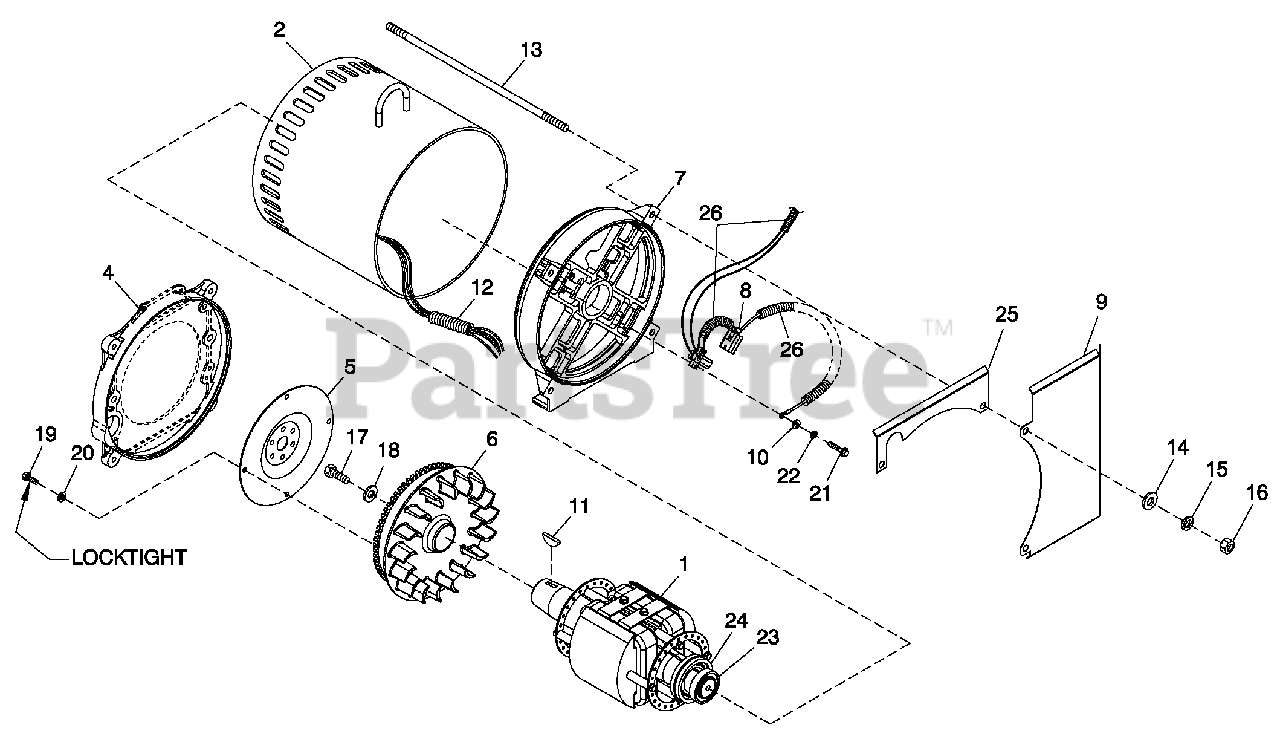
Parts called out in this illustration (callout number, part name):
1	ROTOR-2390-35KD1 CPL
2	STATOR-2390-35AD1 CPL
4	ENGINE ADAPTER
5	FLEXPLATE
6	ASSY FLYWHEEL CPL W/40MM FAN B
7	REAR BEARING CARRIER 390/DRCT
8	ASSY BRUSH HOLDER 390/HSB
9	GUARD REAR BEARING CARRIER
10	WASHER FLAT #8 ZINC
11	KEY WOODRUFF #E
12	CONDUIT FLEX 1.0" ID (35" LG)
13	STUD M14-2.0 570 G5 ZINC
14	WASHER FLAT M14
15	WASHER LOCK M14
16	NUT HEX M14-2.0 G8 YEL CHR
17	SCREW HHC M16-2.0 X 45 G8.8
18	WASHER FLAT .688 ID X 3.25 OD
19	SCREW HHC M10-1.50 X 16 G10.9
20	WASHER LOCK M10
21	SCREW HHTT M4-0.7 X 25 BP
22	WASHER LOCK #8-M4
23	BALL BEARING-45 MM
24	SLIP RING MACHINED
25	GUARD REAR BEARING CARRIER
26	CONDUIT FLEX .38" ID (60")
